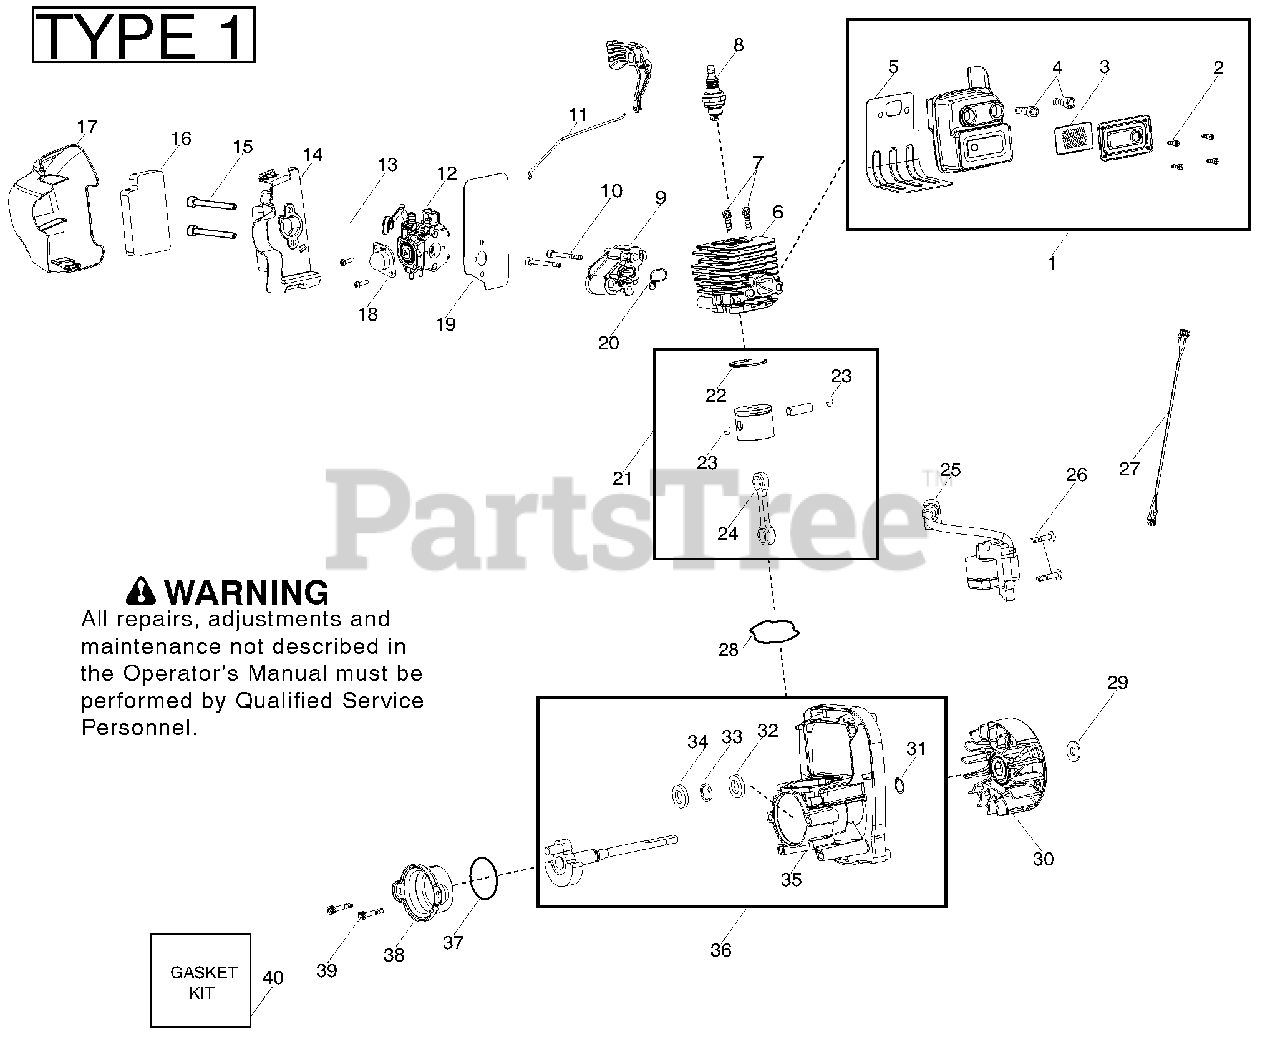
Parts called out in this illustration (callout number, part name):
1	Assy - Muffler
3	Kit - Spark Screen
5	Gasket-Muffler (gasket kit)
6	Cylinder
8	Spark Plug (RCJ-6Y)
9	Adapter - Carb.
11	Linkage - Throttle
12	Kit - Carb. Assy (WT847)
13	Lever- Choke, Gold
13	Lever- Choke, Red
14	Base - Airbox
17	Cover - Air Box Filter
18	Bulb - Purge (walbro 188-16)
19	Gasket (Carb / Adapter) (gasket kit)
20	O-Ring (Adapter / Cylinder) (gasket kit)
21	Kit - Piston / Connecting Rod
22	Ring - Piston
23	Retainer - Wrist Pin
24	Kit - Assy. Connecting Rod
25	Module - Ignition
27	Assy - Wire Harness
28	O-Ring (Cyl/Crankcase) (gasket kit)
30	Assy - Flywheel
31	Retainer - Crankshaft
32	Bearing - Outer
34	Bearing - Inner
35	Assy - Crankcase
36	Assy - Crankcase & Crankshaft
37	O-Ring (Rear Plug) (gasket kit)
38	Assy - Rear Plug
40	Kit - Gasket
